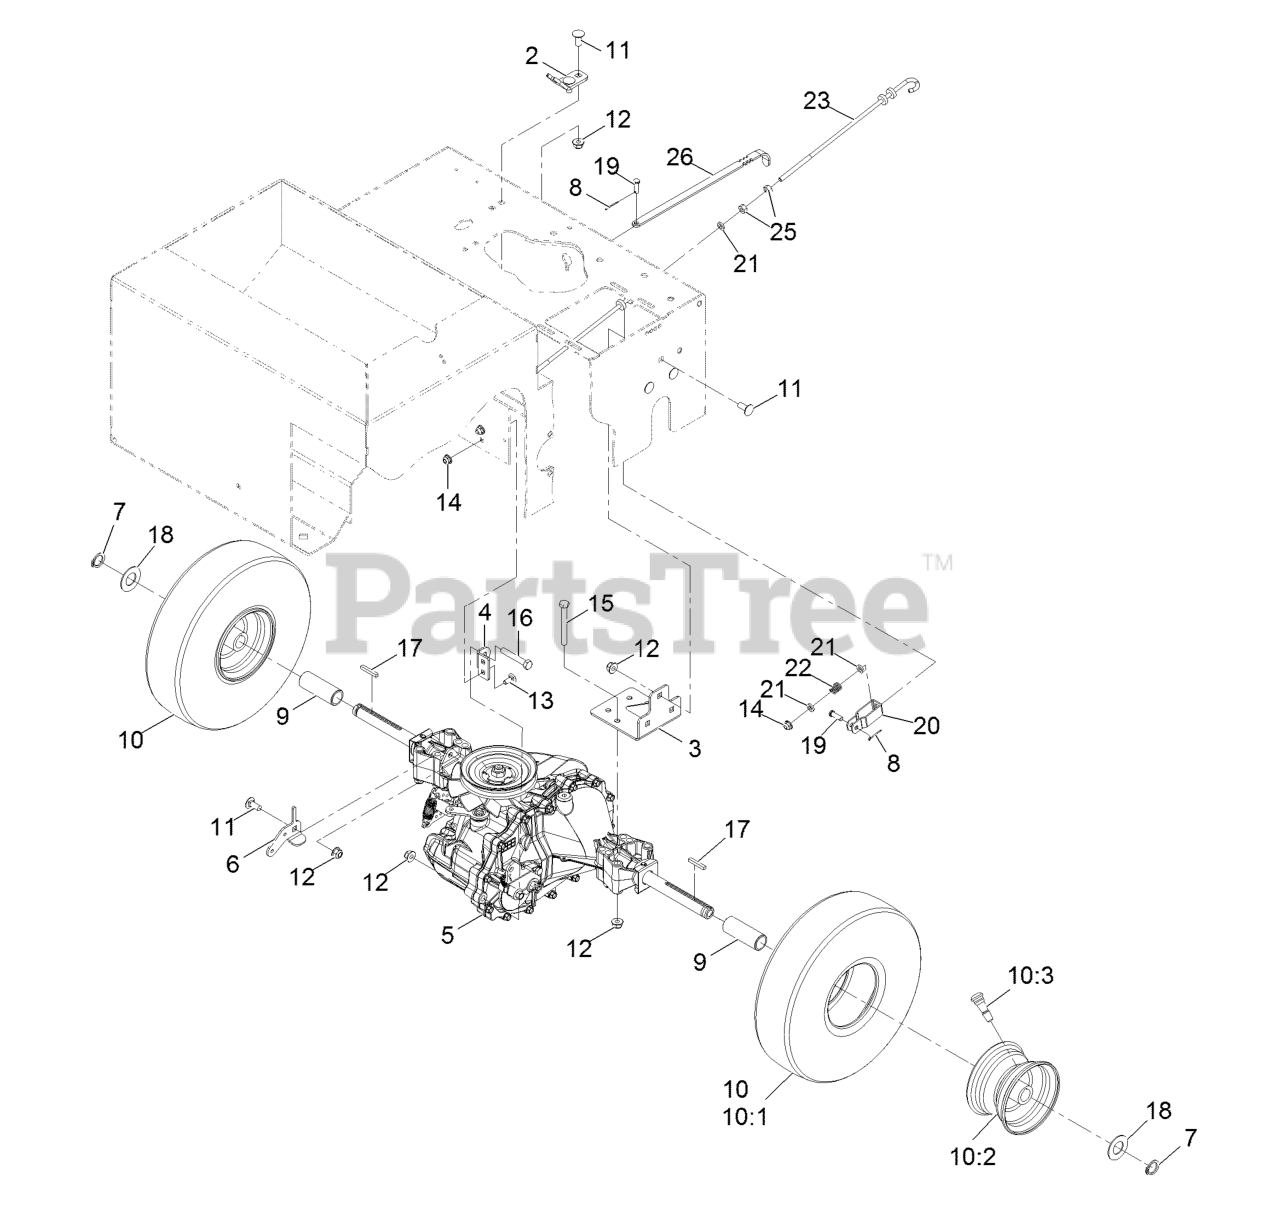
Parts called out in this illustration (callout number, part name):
2	BRACKET-CABLE
3	BRACKET-AXLE
4	BRACKET-TRANSAXLE, TORQUE
5	TRANSAXLE ASM
6	BRACKET-TRANSAXLE
7	RING-RETAINING
8	SCREW-HH
10	WHEEL ASM
10:2	WHEEL-RIM
10:3	VALVE
11	SCREW-CARR
12	NUT-HF, NI
13	SCREW-CARR
15	SCREW-HH
16	SCREW-HH
17	KEY-SQUARE
18	WASHER-FLAT
19	PIN-CLEVIS
21	SPACER-PLATE, PIVOT
22	SPRING-COMPRESSION
23	ROD-BRAKE
25	NUT-HEX
26	LEVER-BYPASS
